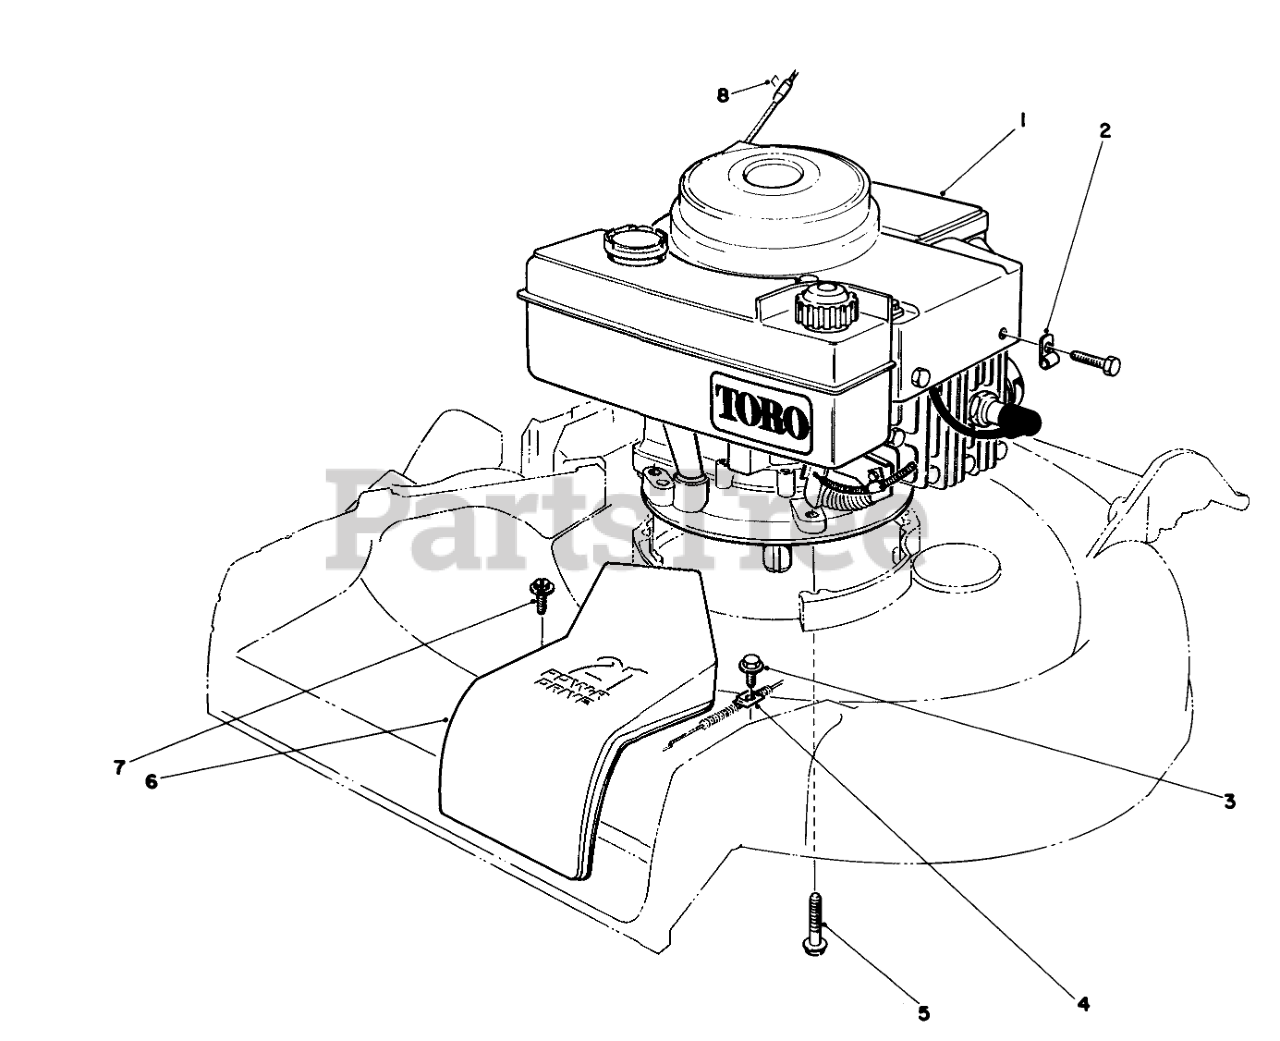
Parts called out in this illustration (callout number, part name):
2	CLAMP
3	SCREW-HWHTF
4	Cable Clamp
5	3/8-16 X 2-3/4 CAPSCR
6	BELT COVER 21" S D
7	SCREW
8	Stable
